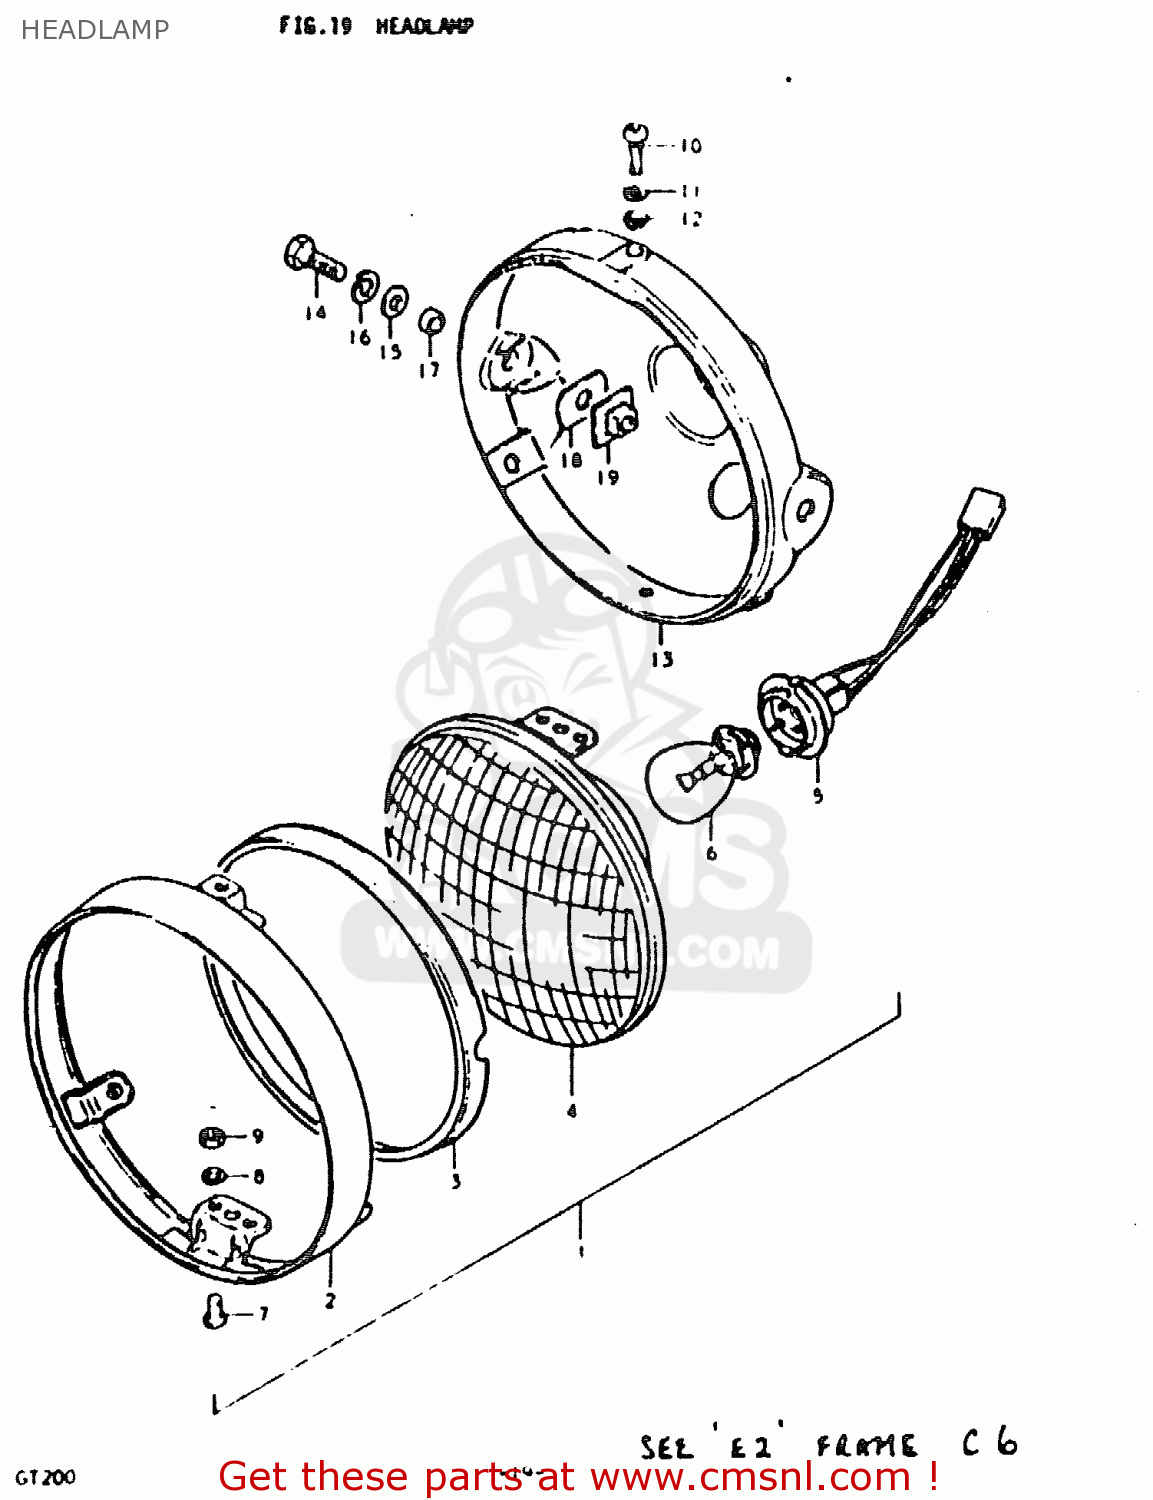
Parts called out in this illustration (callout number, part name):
1	HEADLAMP ASSY
2	RIM
3	RETAINER,HEADLAMP
4	UNIT
5	SOCKET
6	BULB 12V35/35W
7	SCREW
8	LOCK WASHER
9	NUT
10	SCREW
11	WASHER,LOCK
12	WASHER
13	HOUSING,HEADLAMP(BLACK)
14	BOLT
15	WASHER
16	LOCK WASHER
17	SPACER (8.8X12X7)
18	CUSHION
19	PLATE,HEADLAMP HOUSING
